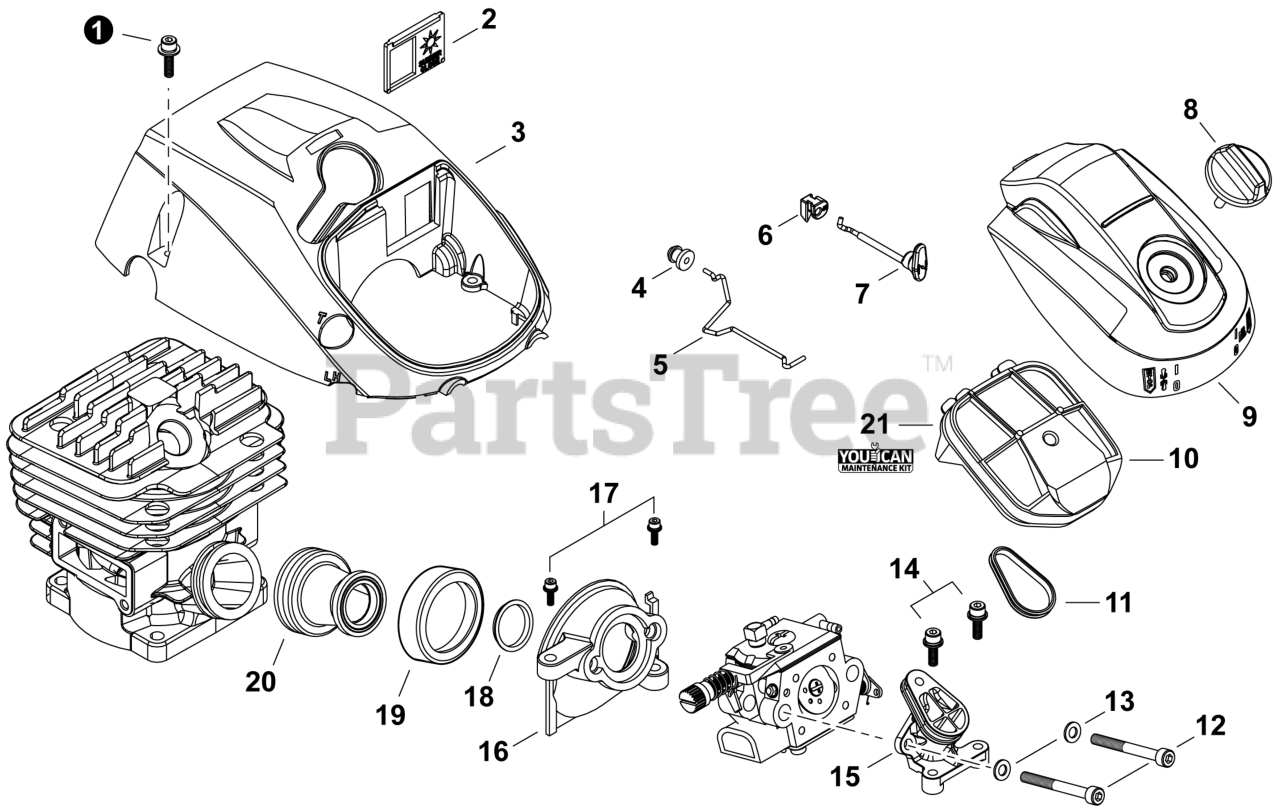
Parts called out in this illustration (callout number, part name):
1	BOLT M4x14
2	PLATE, SHUTTER
3	COVER, ENGINE
4	GROMMET
5	ROD, THROTTLE
6	GROMMET, CHOKE
7	ROD, CHOKE
8	THUMBSCREW
9	COVER, AIR FILTER
10	FILTER ASSY, AIR, FLOCKED
12	BOLT M5x48
13	WASHER, FLAT 5.5x10x0.8
14	BOLT M4x16
15	ADAPTOR, AIR FILTER
16	INSULATOR, INTAKE
17	BOLT M4x16
18	COLLAR 16
19	HOLDER, BELLOWS
20	BELLOWS, INTAKE
21	TUNE-UP KIT - YOUCANT
